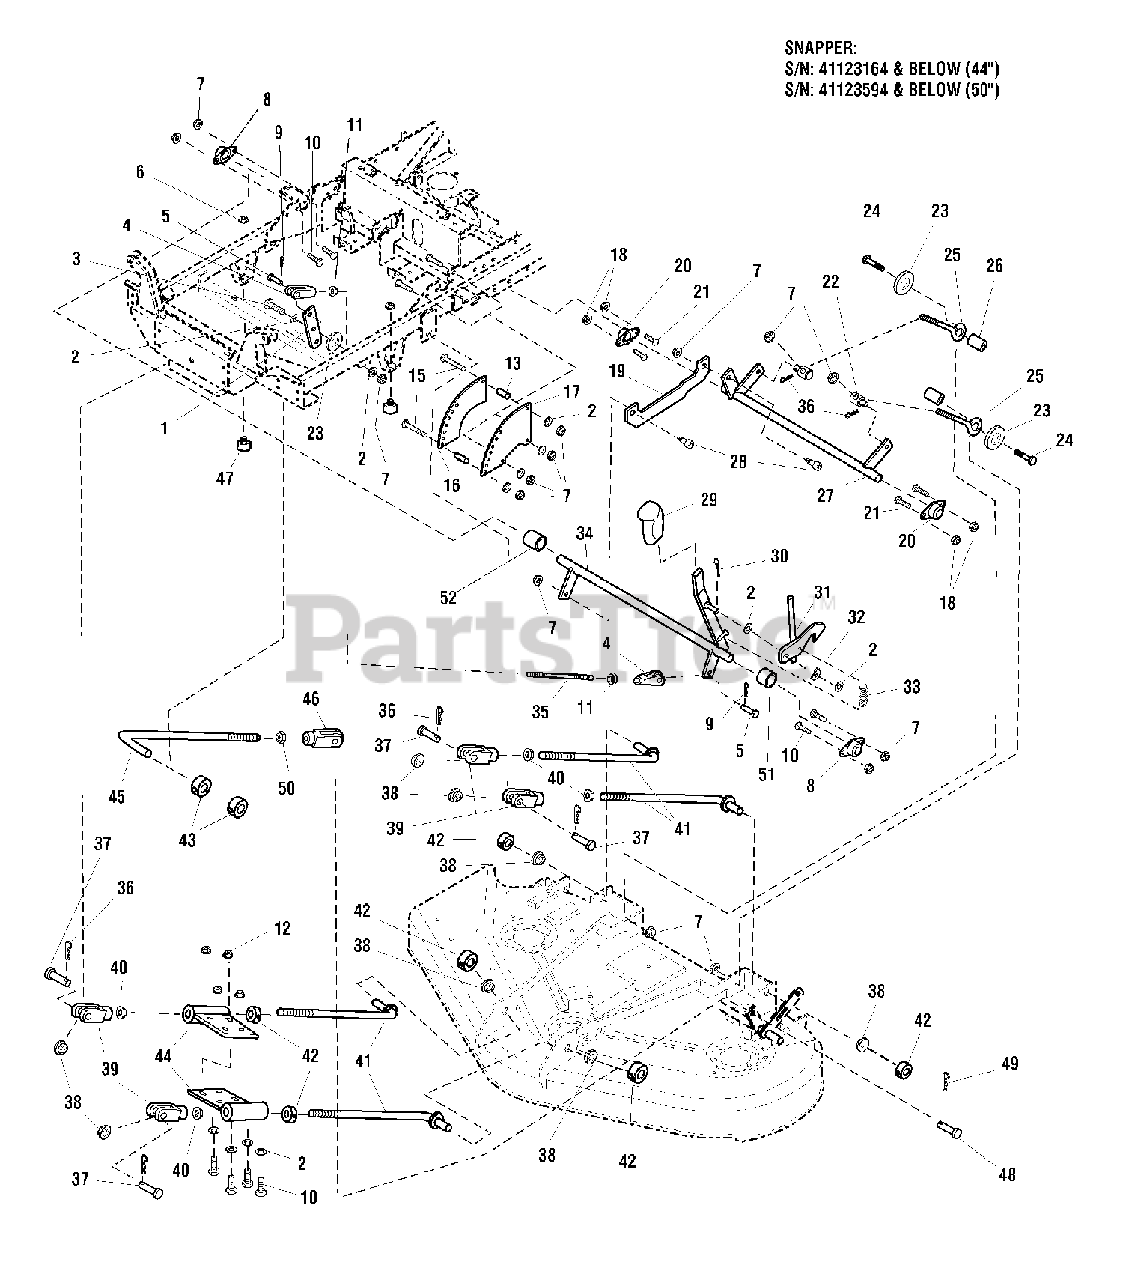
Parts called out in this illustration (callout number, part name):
1	* REVERSING LINK
2	WASHER, 3/8, SAE
3	BOLT, 3/8-16 X 1-1/2" GD5 CZ
6	HEX NUT, SERRATED FLANGE, 1/4-20
7	NUT, HEX NYLON LOCK, 3/8-16
8	BRONZE FLANGE BEARING, 3/4"
9	* COTTER PIN
10	BOLT, 3/8-16 X 3/4" GD5 CZ
12	HEX NUT, SERRATED FLANGE, 3/8-16
13	SPACER
15	BOLT, 3/8-16 X 2-1/2" GD5 CZ
16	DECK HEIGHT PLATE, INNER
17	DECK HEIGHT PLATE,OUTER
18	HEX NUT, NYLON LOC, 5/16-18
19	DECK LIFT LINK
20	BRONZE FLANGE BUSHING
21	BOLT, 5/16-18 X 3/4 GD5
22	ADJUSTER, BRAKE LINKAGE
23	WASHER, 1-3/4 OD X .390 ID
24	BOLT, 3/8-16 X 2-1/4" GD5 CZ
25	EYE BOLT, 3/8-16
26	SPACER
27	REAR DECK LIFT SHAFT
28	BOLT, 1/2" X 3/8" SHOULDER
29	HANDLE COVER
30	COTTER PIN, 3/16 X 1-1/2
31	DECK LOCK
32	SPRING WASHER, 3/8
33	EXTENSION SPRING
34	DECK HEIGHT SHAFT
36	HAIRPIN
37	PIN, CLEVIS, 1/2 X 1-1/2
38	SUPPORT BUSHING
39	CLEVIS, 1/2-20
40	HEX JAM NUT, 1/2-20
41	DECK HANGER ROD
42	SPLIT COLLAR, 1/2"
44	DECK STABILIZER
45	* ROLLER CONNECTING ROD (44" DECK)
47	RUBBER BUMPER, 1/4-20
49	* HAIRPIN
51	SPACER, .76 X 1.00 X .50
52	SPACER, .76 X 1.00 X 1.00
